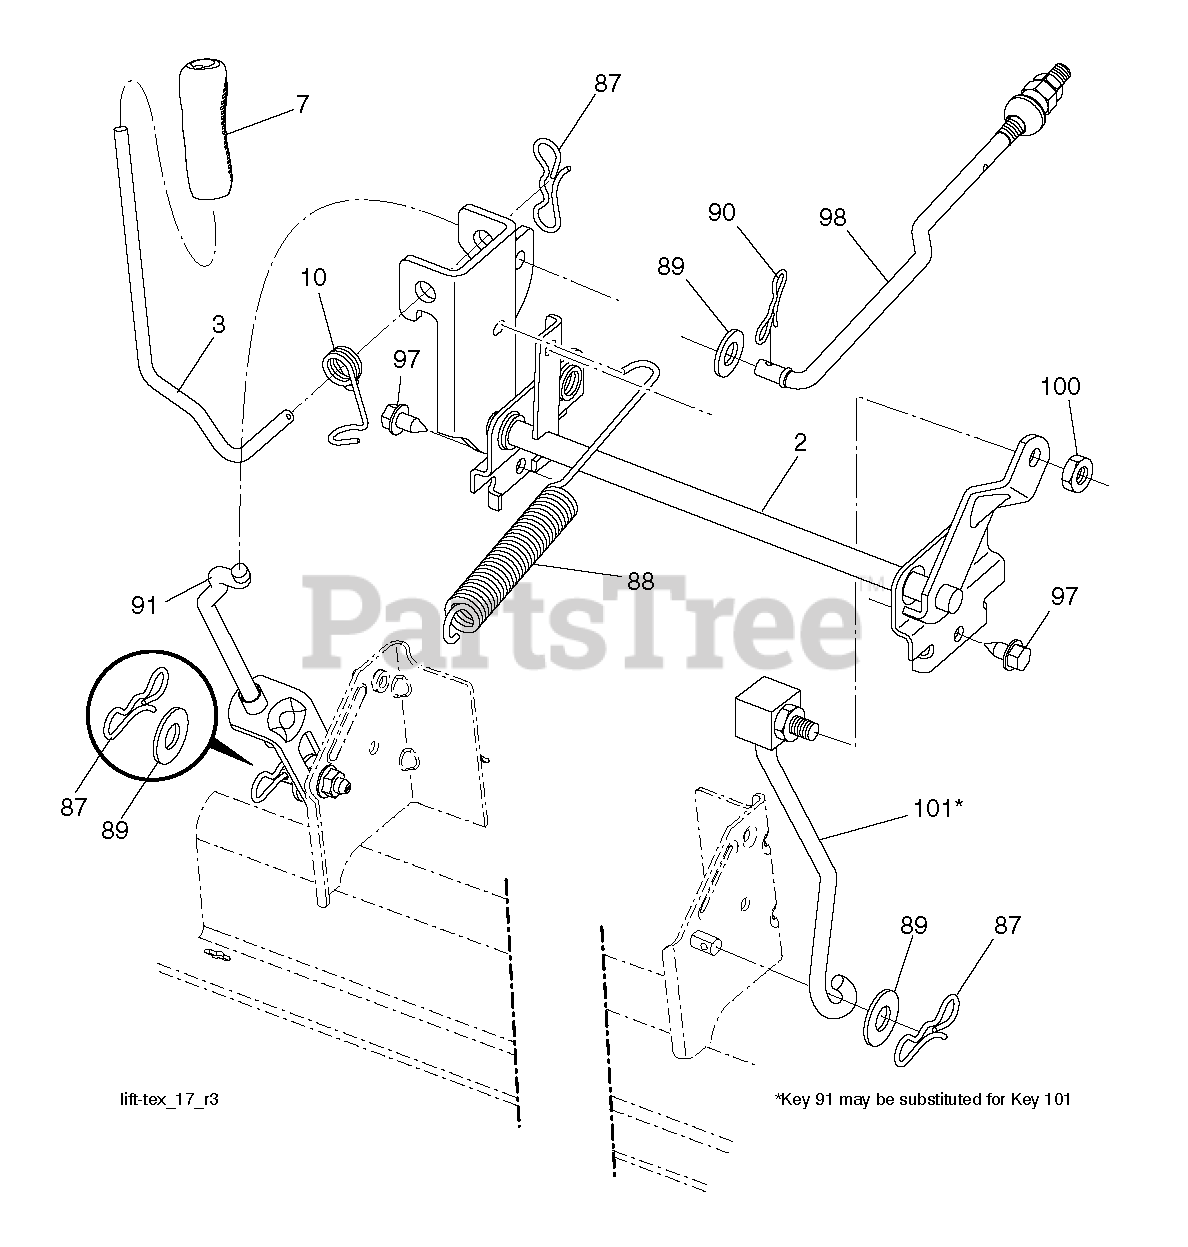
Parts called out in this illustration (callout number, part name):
2	SHAFT.ASM.CROSS.LIFT
3	LEVER.LIFT.HANDLE.LT
7	GRIP.HANDLE.LIFT.PVC.BLACK
10	SPRING.TORSION.LIFT.HANDLE
87	PIN.COTTER.7/16.BOW TI
88	SPRING.LIFT.ASSIST
89	WASHER.CLEAR.ZINC
90	PIN.COTTER.5/16.BOW TI
91	LINK.ASM.LIFT.REAR
97	SCREW, 3/8-16X3/4
98	LINK.ASM.SUSP.FRONT.MW
100	LOCKNUT
101	LINK.ASM.LIFT.FIXE.38/42/46"
